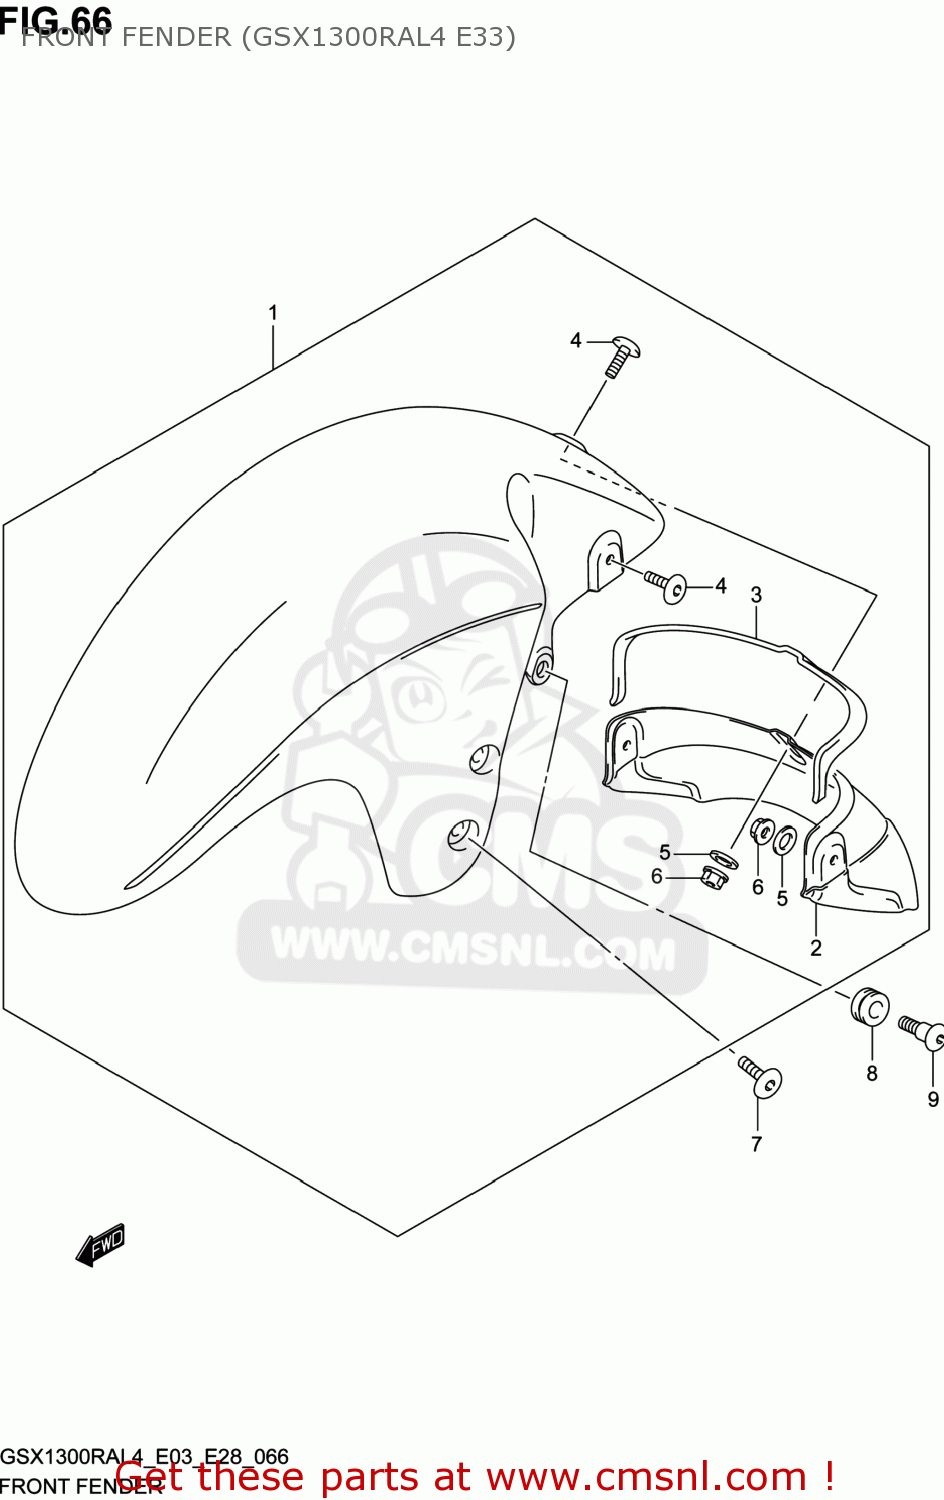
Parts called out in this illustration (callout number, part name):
1	FENDER ASSY,FRONT
2	MUDGUARD,FR FENDER
3	CUSHION
4	SCREW(6X16)
5	WASHER(6.5X16X1)
6	NUT
7	SCREW(6X16)
8	CUSHION
9	SCREW(6X16)
